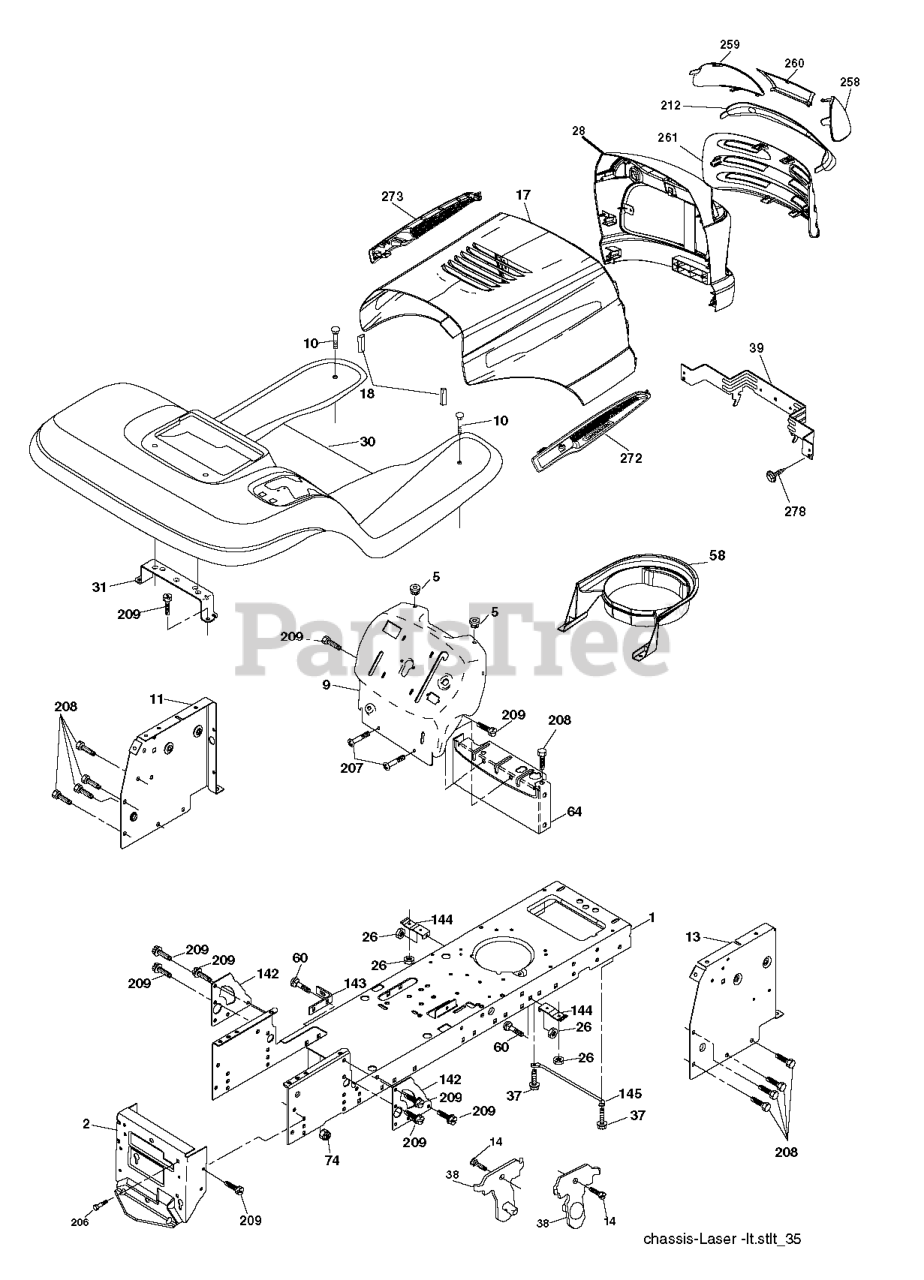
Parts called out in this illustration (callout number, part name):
1	CHASSIS STAMPING
2	DRAWBAR, 12GA
5	BUMPER.RUBBER.HOOD
9	FENDER.STL.W/O CUPHLDR.ROS.422
10	BOLT D
11	PANEL.DASH.LH.LTX
13	PANEL DASH RH
17	VENT.HOOD.LASER.III
18	BUMPER.HOOD.LARGE.1.75"
26	NUT
31	BRACKET.SUPPORT.FENDER
37	Screw 5/16-18 x 1/2 Hex, Self Tapping 5/16-18 x 1/2
38	BRACKET.ASM.PIVOT.MOWER.REAR
39	BRACKET PIVOT LASER
60	Bolt - Rd. Hd. Sq. Neckiage 3/8 16 x 3/4
64	DASH LOWER
142	PLATE REINFORCEMENT
143	BRACKET, SWAYBAR CHASSIS
144	BRKT, FOOT REST
145	ROD PIVOT CHASSIS/HOOD
206	SHOULDER BOLT 5/16-18TT
207	SCREW, 5/16-18 X 1/2
208	SCREW 3/8-16X1/2
209	SCREW, 3/8-16X3/4
212	INSERT.LENS.REFLECTIVE
258	LENS LH
259	LENS LH
260	COVER.LENS.HUSQ.LASER
272	VENT.HOOD.LASER.
273	VENT.HOOD.LASER.
278	SCREW
